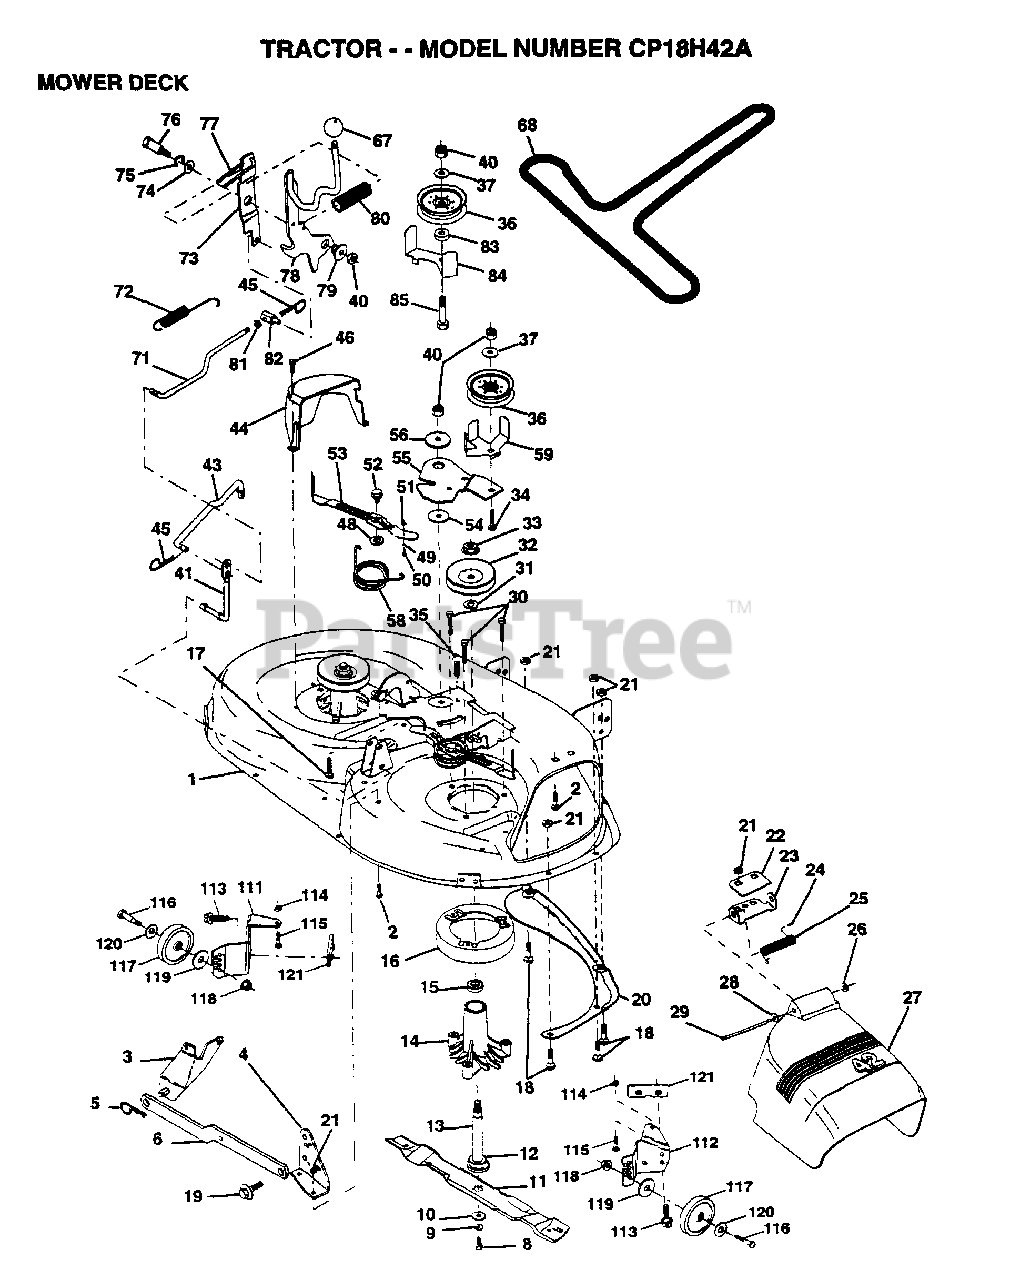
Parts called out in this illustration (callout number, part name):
1	DECK.WELD.42.
2	BOLT
3	BRKT ASM SWAY BAR
4	BRKT DECK SW BAR
8	BLADE BOLT
10	WASHER.HARD.BLADE
11	"BLADE.42"" HIPERF"
12	BEARING.BALL
14	HSG ASM MANDREL
15	BEARING
16	STRIPPER RND MWR
17	BOLT RDHD 3/8-16
18	BOLT
19	BOLT SHD 5/16-18
22	STIFFENER BRKT
23	DEFLECTOR BRKT
24	CAP-SLEEVE LT
25	SPRING TORSION
26	NUT PUSH M
27	DEFLECTOR.SHIELD
28	WASHER
29	HINGE ROD
31	WASHER
34	BOLT
35	XMAS TREE FASTNER
36	FLAT IDLER PULLEY
37	WASHER
41	PIVOT ROD
43	ROD CLUTCH W/NIBS
44	GUARD MAND LH BLK
45	RETAINER M
46	SCREW.1/4-20X5/8
48	HARD SMALL WASHER
50	SHOULDER BOLT
51	LOCKNUT
52	BOLT.SHLD.5/16-18
53	BRAKE PAD ARM ASM
54	HARDENED WASHER
56	SPACER RETAINER
58	SPRING TORSN BRAK
59	GUARD IDLER TUV
67	KNOB T (1/2-HOLE)
68	BELT.V.T-PATH
71	ROD CLUTCH 38/42
72	RETURN SPRING
73	CLUTCH ARM SECOND
74	WASHER
75	RING
76	SHOULDER BOLT
77	SPRING KEEPER
78	LEVER ASM CLT PRM
79	BUSHING
81	NUT
82	TRUNION ADJ
83	WASHER
85	BOLT RDHD 3/8-16
113	SCREW
116	BOLT M
117	WHEEL.GAGE.BLK.PL
118	LOCKNUT
119	WASHER
120	WASHER
121	BRACKET.EXTRD.GWL
